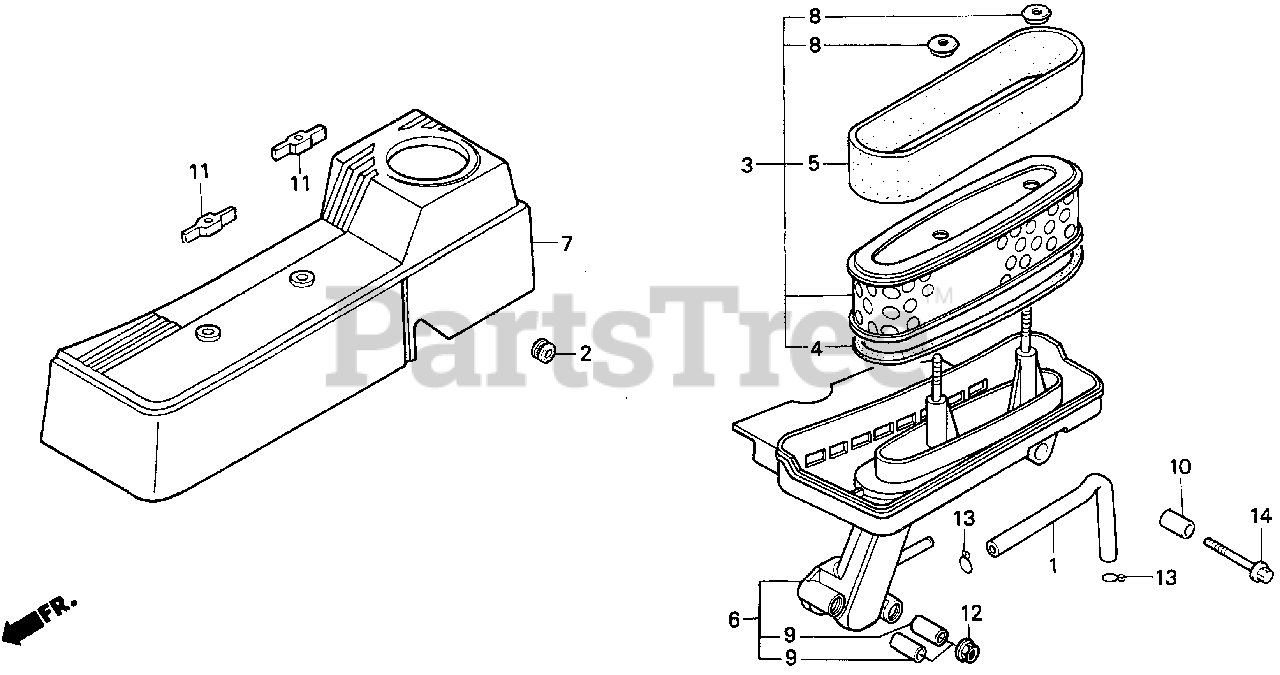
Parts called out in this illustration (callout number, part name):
1	TUBE, BREATHER
2	GROMMET, CHOKE ROD
3	ELEMENT, AIR CLEANER
4	GASKET, ELEMENT
5	FILTER (OUTER)
6	HOUSING, AIR CLEANER
7	COVER, AIR CLEANER
8	GROMMET, AIR CLEANER
9	COLLAR, AIR CLEANER Use from Engine SN 1786085.
9	COLLAR, AIR CLEANER
10	COLLAR B, AIR CLEANER
11	WINGNUT (6MM)
12	NUT, FLANGE (6MM)
13	CLIP, TUBE (B12) Use from Engine SN 2086984.
14	BOLT, FLANGE (6X35)
